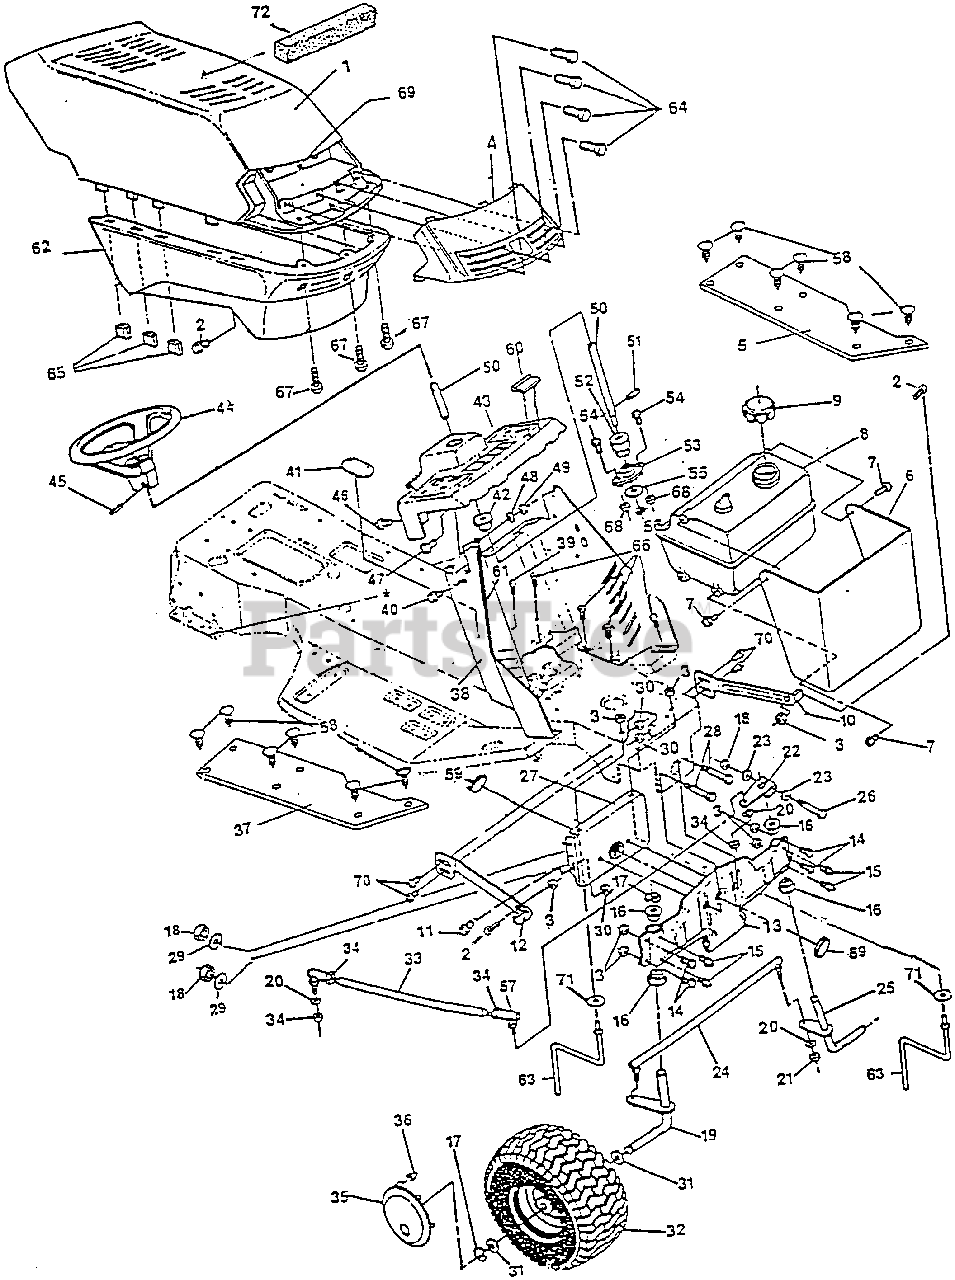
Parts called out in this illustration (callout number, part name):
2	Shoulder Bolt, 5/16-18 Thd.
3	Nut, Hx, Ctrlk, 5/16-18 Thd.
4	Lens, Headlight
5	Assembly, Foot Pad L.H.
6	Heat Shield
7	Screw, Hx Hd, Plastite 1/4 Dia. x 3/4 In
8	Tank, Gas 1.5 Gal W/Sensor
8	Low Fuel Sensor
10	Bracket, Hood L.H.
11	Screw, Hx Hd, 5/16 -18 x 3/4 In.
12	Bracket, Hood R.H.
13	Front Axle W/Bearings
14	Screw, Hx Hd, 5/16-18 x 5/8 In.
15	Grease Fitting
16	Bearing, Spindle
18	Nut, Hx, Ctrlk, 3/8-16 Thd.
19	Spindle, R.H.
20	Washer, Split, Lock 3/8 In.
21	Nut, Hx, 3/8-24 Thd.
22	Steering Arm, Upper
23	Washer, Flat, 25/64 In.
24	Assembly, Tie Rod
25	Spindle, L.H.
26	Screw, Hx Hd, 3/8-16 x 2-1/2 In.
27	Support Bracket, Front Axle
28	Screw, Hx Hd, 3/8-16 x 3 In.
29	Washer, Spring
30	Nut, Hx, Wd Fl Lk 5/16-18 Thd.
31	Washer, Flat, 3/4 In.
32	Wheel & Tire Assembly, Front Tire
32	Wheel/With Bearing
32	Valve Stem
34	Nut, Hx, Jam, 3/8-24 Thd.
35	Hubcap, Front
36	Clip, Hubcap
37	Assembly, Foot Pad R.H.
38	Dash, Lower
39	Screw, Tap, 5/16-18 x 3/8 In.
40	Screw, Self-Tap, 1/4-20 x 1/2 In.
42	Bushing, Upper Steering
43	Dash, Upper
44	Steering Wheel
45	Pin, Spring, 1/4 x 2 In.
46	Screw, Tap, 1/4-20 x 1/2 In.
47	Screw, Hx Hd, 1/4-20 x 5/8 In.
48	Washer, Flat, 9/32 In.
49	Nut, Hx, Ctrlk, 1/4-20 Thd.
50	Shaft, Steering
51	Pin, Dowel
52	Pinion, Steering
53	Bearing, Flange
54	Screw, 5/16-24x.75 Sq.
55	Washer, Flat, 1/2 In.
57	Ball, Joint, 3/8 Thd.
58	Ratchet Fastener
59	Plug, Front Axle
60	Bumper, Hood/Dash
61	Wide Trim 18"
63	Belt Guide
64	Screw, #4-24 x 112 In.
65	Clip, Tinnerman
66	Screw, 5/16-18 x .50 In.
67	Screw, #10 x 1/2 In.
68	Nut, 5/16-24 HXWdfllk
69	Decal, Reflector Ver II, Hood
70	Screw, Hex Fl, 5/16-18 x 3/4 In.
71	Washer, Internal Tooth
72	Foam, Hood Baffle
